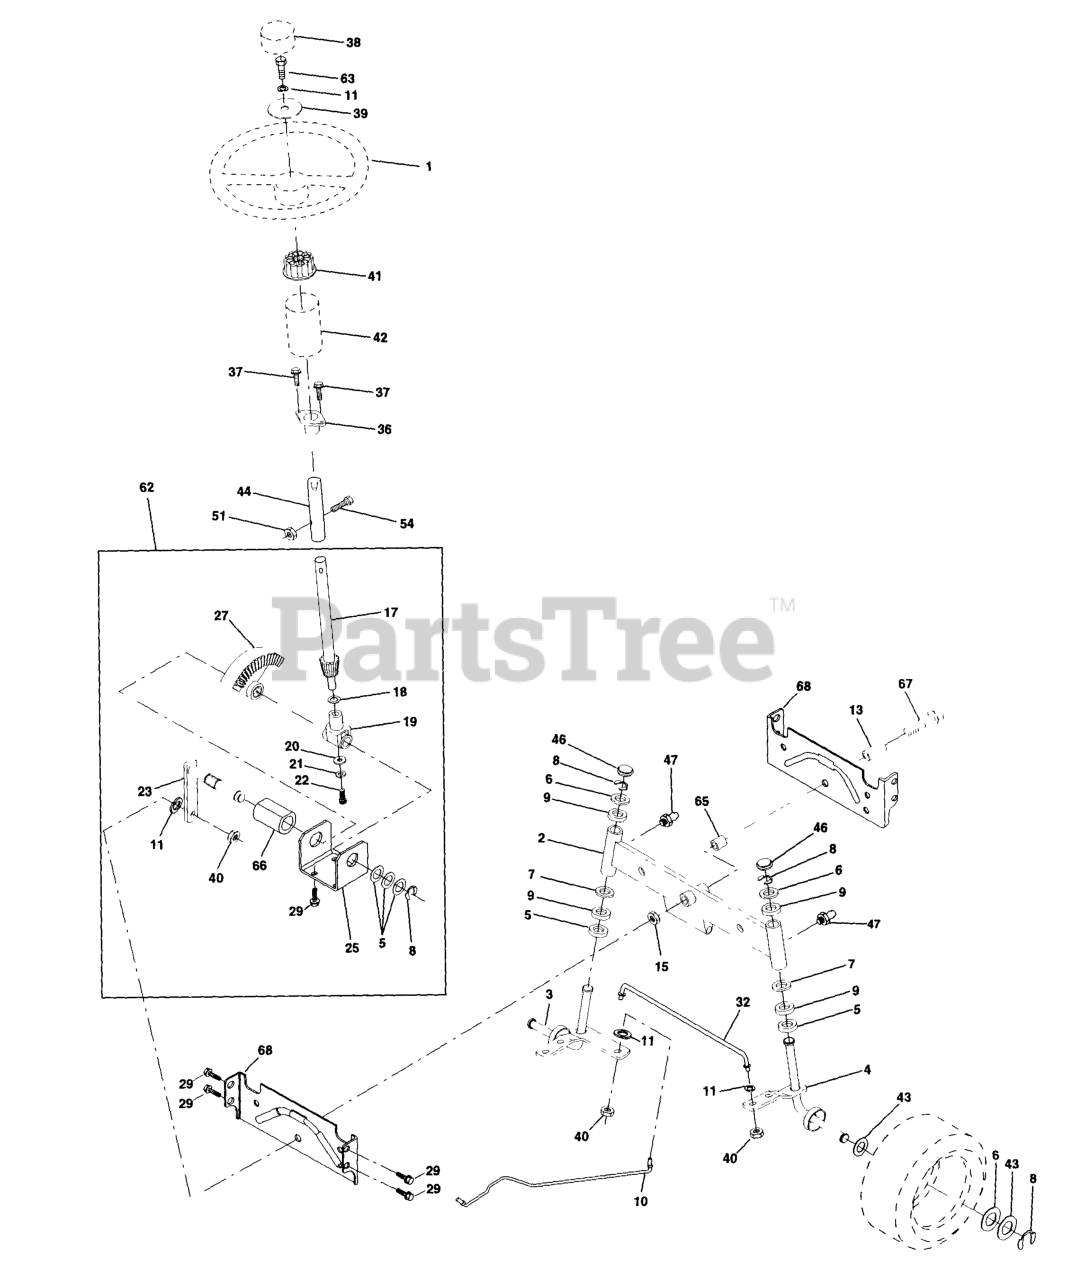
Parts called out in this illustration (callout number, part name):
1	STEERING WHEEL
2	FRONT AXLE ASSY
3	SPINDLE ASS'Y LH
4	SPINDLE ASM RH
5	THRUST WASHER
9	BRNG T
10	LINK.DRAG.DROPPED.LT
11	WASHER, LOCK 3/8
13	BEARING AXLE
15	NUT-LOC,FLANGE LT
17	SHAFT ASM STEERING
18	THRUST WASHER
19	SHAFT,SUPPORT
20	WASHER
21	LOCKWASHER
22	SCREW
23	SHAFT PITMAN
25	BRACKET STEERING
27	GEAR.SECTOR
29	SCREW
32	ROD ASSY/TIE BALL
36	BUSHING, STEERING
37	SCREW.TT.#10-32X.5.3/8.FLANGE
38	INSERT,STR WHEEL
39	WASHER T
40	GRIPCO NUT
41	ADAPTER LT
42	BOOT, STEERING
44	EXT SHAFT STEERING
46	CAP.SPINDLE.BLACK
47	ZERK M
51	NUT.71038.31-18.HEX.NYLOCK
54	BOLT.5/16-18X1-1/4 FULL.THREAD
62	KIT, STEERING ASSEMBLY
63	BOLT
65	SPACER AXLE
66	BEARING ARM
67	Bolt, Fin Hex 5/8-11 UNC x 2-3/4
68	AXLE, BRACE
